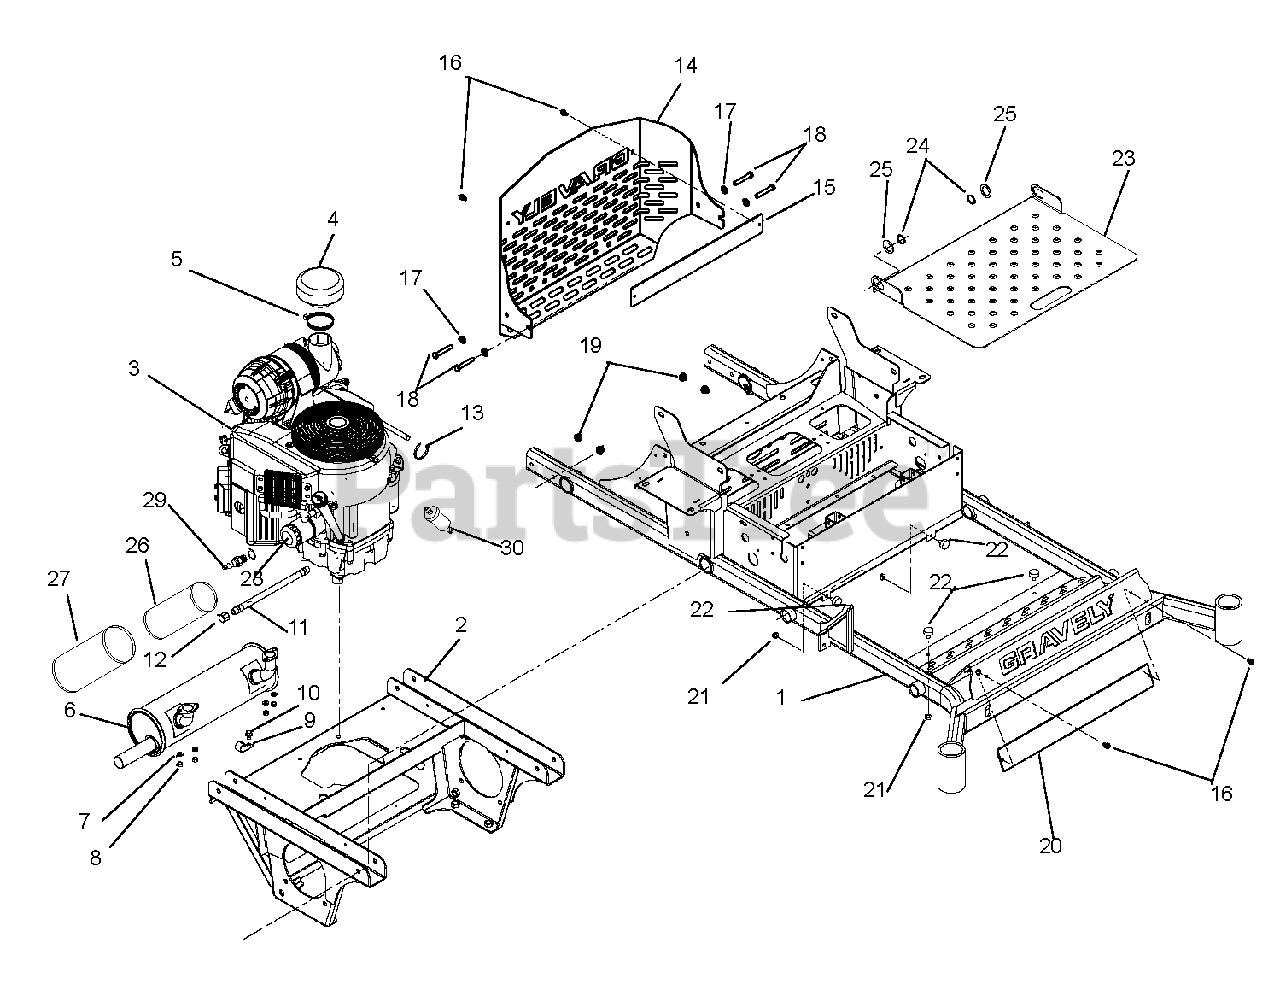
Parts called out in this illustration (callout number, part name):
1	Weldment, 52" – 66" 200PT Main Frame
2	Weldment, 200PT Axle/Engine Frame
3	Engine, Kawasaki 27HP (992201, 198)
4	Rain Cap, Air Cleaner (992201, 203, 197, 198)
5	Clamp, Hose 2.75 DIA Worm (992201, 203, 197, 198)
6	Muffler, 27 – 31 Kawasaki (992201, 203, 198)
7	Washer, Lock .31 x .078 REG YWZC
8	Nut, Locking Top M8-1.25 YWZC
10	Screw, Tap .38-16 x .50 Hex Washer Head TR YWZ
11	Hose, Hydraulic .38-11-0K M6N0-M6N0 (992201, 203, 198)
12	Pipe Cap 3/8 NPT Female
13	Cable Tie LG 5-1/2
14	Weldment, Bumper, Pro-Turn 200
15	Plate, Bumper, Pro-Turn 200
16	Screw, Tap Hex Washer Head .25-20 x .50 TR YWZ
17	Washer, Flat Steel .406 x .812 x .065 YWZ
18	Bolt, Hex .38-16 x 2.25 Grade 5 YWZC
19	Nut, Locking Nyloc Flange .38-16 YWZC
20	Plate, Bumper Name Backer
21	Nut, Spin Lock Flange .312-18
22	Bumper, Rubber
23	Inspection Panel
24	Ring, Retaining, External 1.00 x .078
25	Washer, Flat Steel 1.010 x 1.505 x .062
26	Element, Inner Safety
27	Element, Outer Primary
28	Oil Filter
29	Spark Plug
30	Fuel Filter
